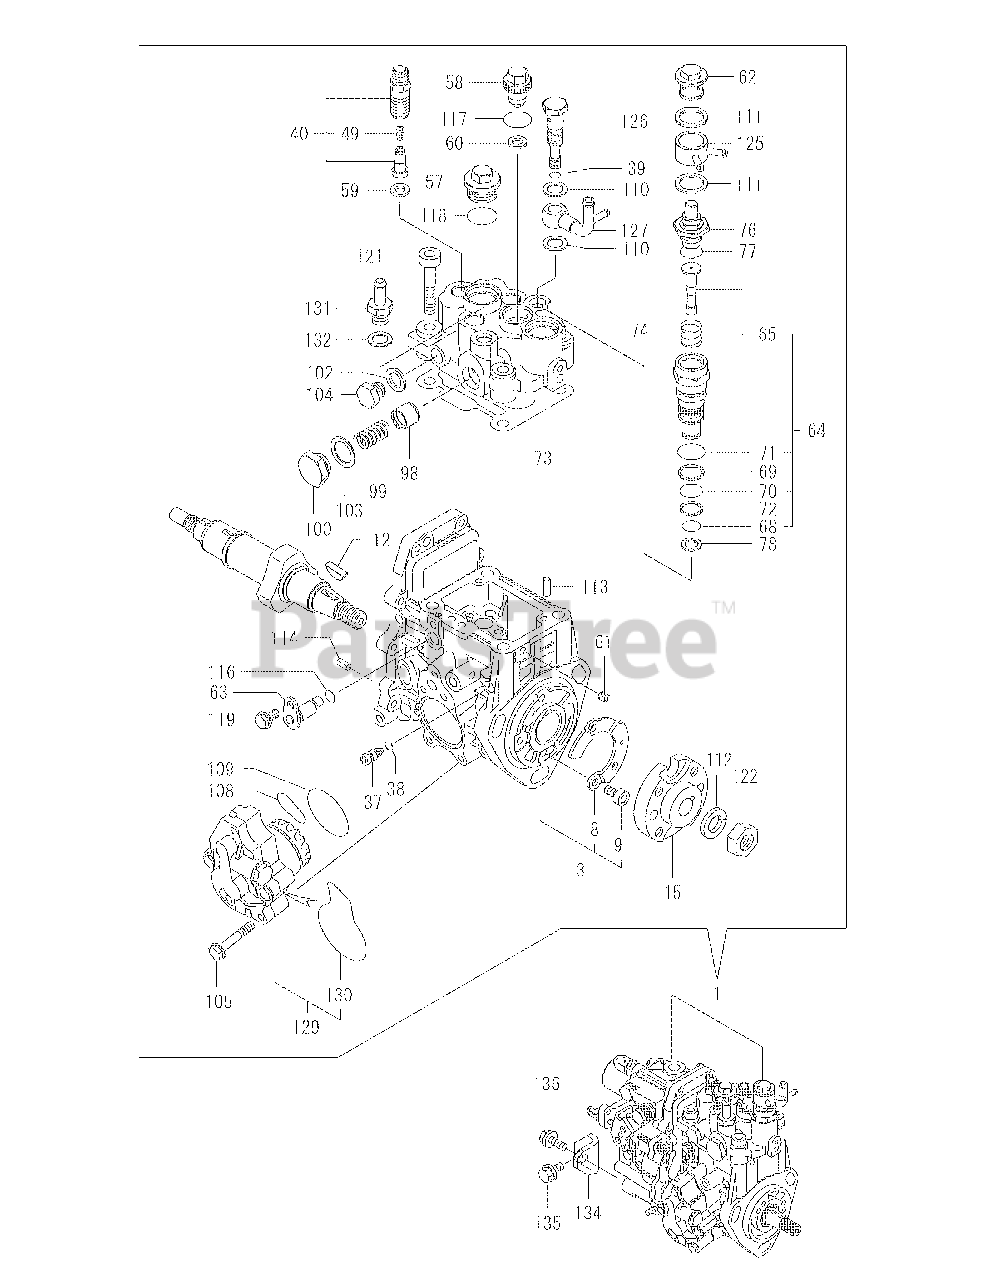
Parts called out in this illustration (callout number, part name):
1	Injection Pump Assembly
3	Pump Assembly Body
12	Woodruff Key, 4 x 16
15	Hub-Inj Pump Gear Cam
37	Tappet Stopper
40	Delivery Setting
49	Delivery Spring
59	Barrel Plug (PK)
60	Barrel Plug (PK)
62	Water Pump Plug
65	Complete Timer
71	Packing, 19020
72	Back-Up Ring, T2 P 15
76	Thermostat Element
99	Actuator Spring
102	Seal Washer, 12
109	O-Ring, 4E S42
110	Seal Washer, 12
112	Spring Washer, 14
113	Parallel Pin, 5 x 14
114	Spring Pin, 5 x 10
116	O-Ring, 1A P-7.0
117	Packing, 19018
118	Packing, 19020
125	Cooling Water Joint
126	Over-Flow Joint
127	Over-Flow Joint
129	Fuel Feed Pump Assembly
132	Seal Washer, 12
